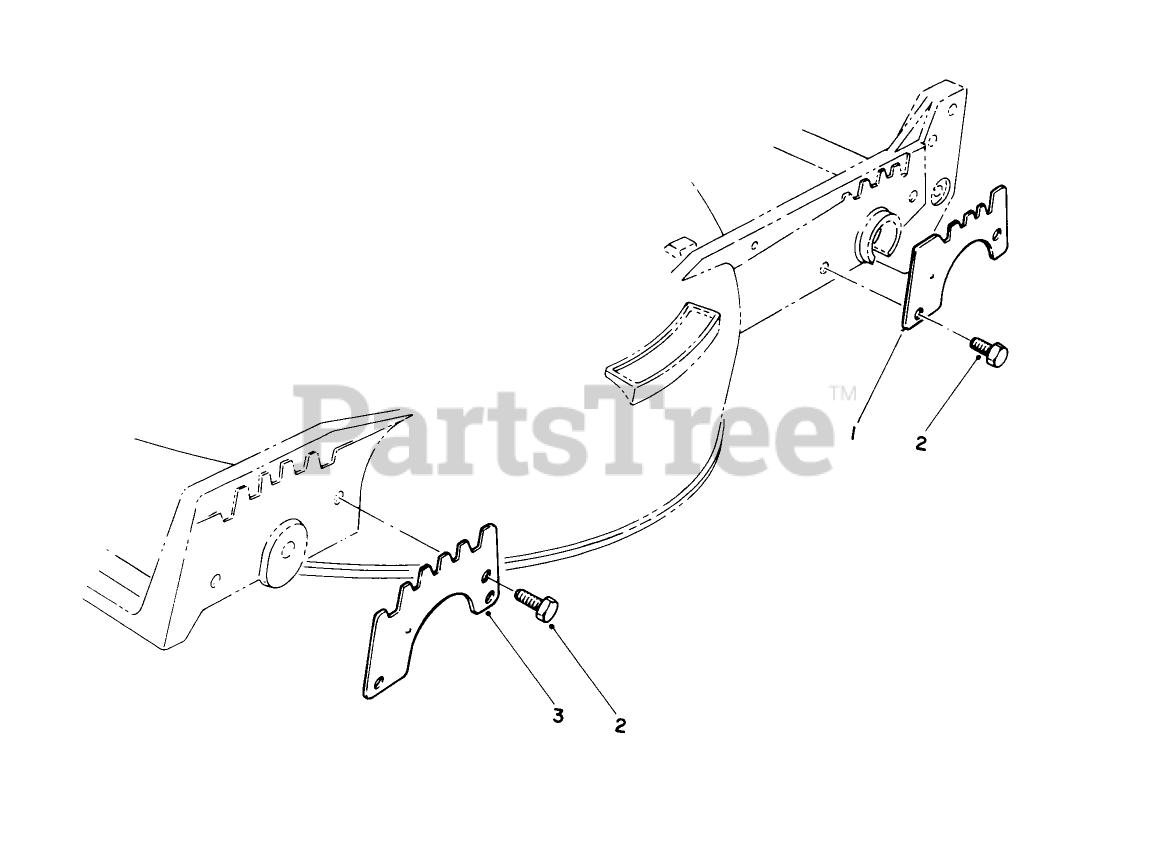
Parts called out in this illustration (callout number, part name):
1	WEAR PLATE,REAR
2	SCREW-HWH
3	WEAR PLATE
